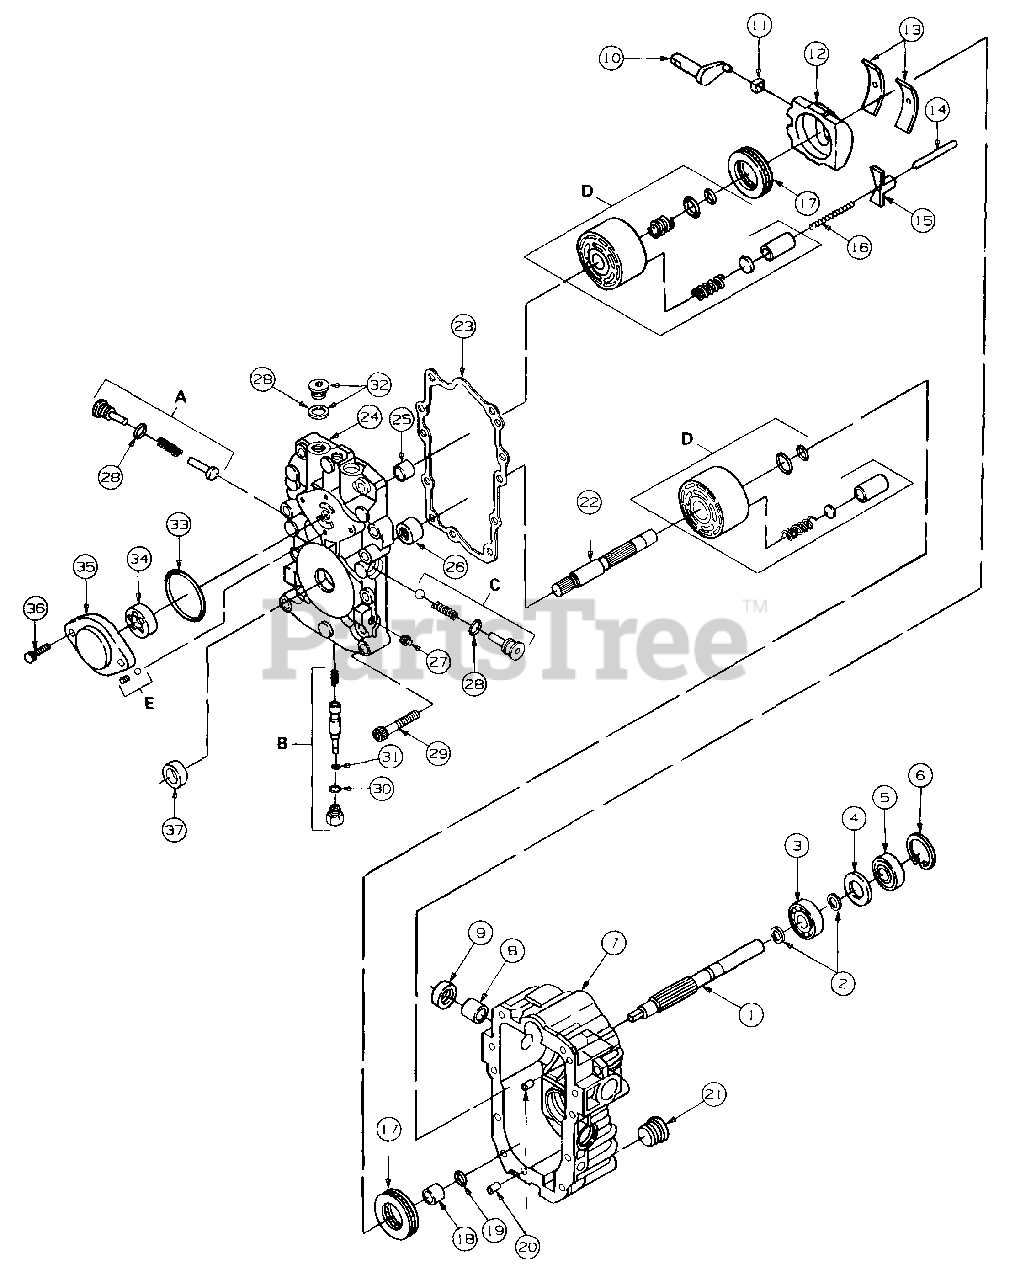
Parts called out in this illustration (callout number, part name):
1	Shaft, Pump
2	Ring, Retaining
3	Bearing, Ball
6	Ring, Retaining
7	Housing Assy
8	Bearing, Journal
10	Arm, Trunnion
11	Guide, Slot
13	Bearing, Cradle
15	Leveler, Swashplate
16	Spring, Leveler
17	Bearing, Thrust
18	Bearing, Journal
19	Washer, Thrust
22	Shaft, Motor
23	Gasket, CenterSection
24	Center Section Assy
25	Bearing, Journal
26	Bearing, Needle
29	Screw, Socket Hd
34	Gerotor Assy
35	Housing, Charge Pump
36	Screw, Socket Hd
A	Kit, Orificed Check Valve
B	Kit, Bypass Valve
C	Kit, Check Valve
D	Kit, Cylinder Block
E	Kit, Charge Relief Valve
